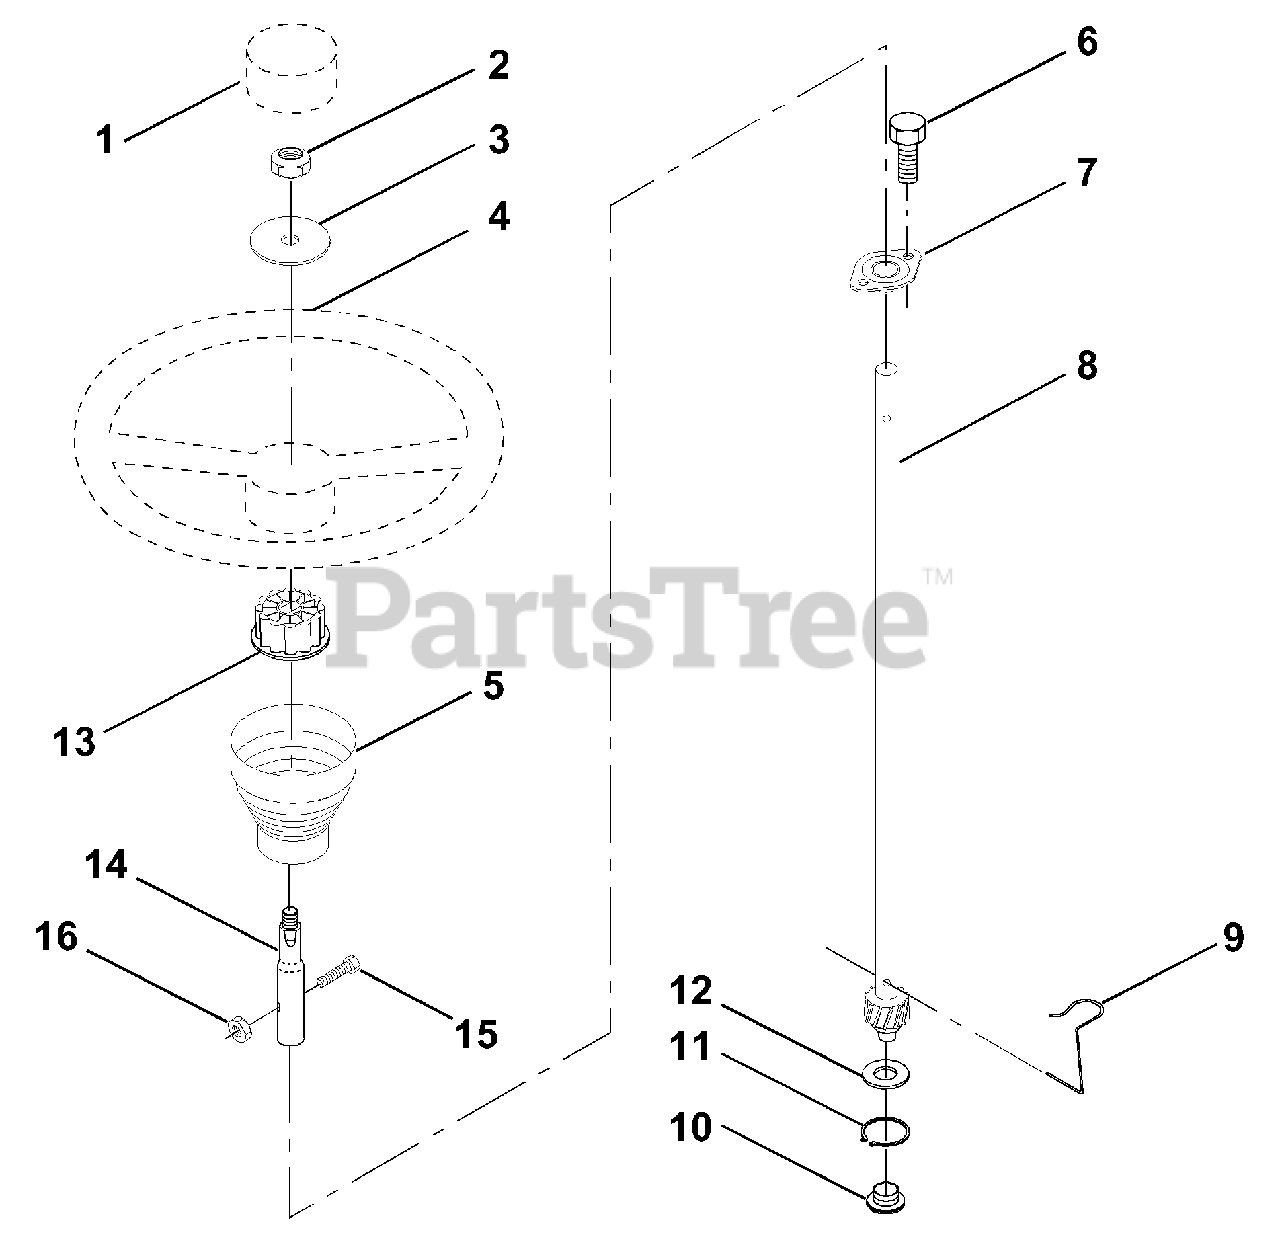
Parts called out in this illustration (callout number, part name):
1	Insert, Wheel, Steering
2	Nut, Lock 3/8-24 UNF
3	Washer 12/32 x 2-3/8 x 8 Ga.
4	Wheel, Steering
5	Sleeve, Steering
6	Screw, Hex #10-16 x 1/2 TY-B
7	Bushing, Steering
8	Shaft, Steering
9	Clip, Steering
10	Bushing, Lower, Steering
11	Ring, Retaining
12	Washer 21/32 x 1 x 16 Ga.
13	Adaptor, Wheel, Steering
14	Extension Shaft
15	Bolt, Fin, Hex 5/16-18 UNC x 1-1/4
16	Nut Lock, Hex W/Ins 5/16-18 UNC
